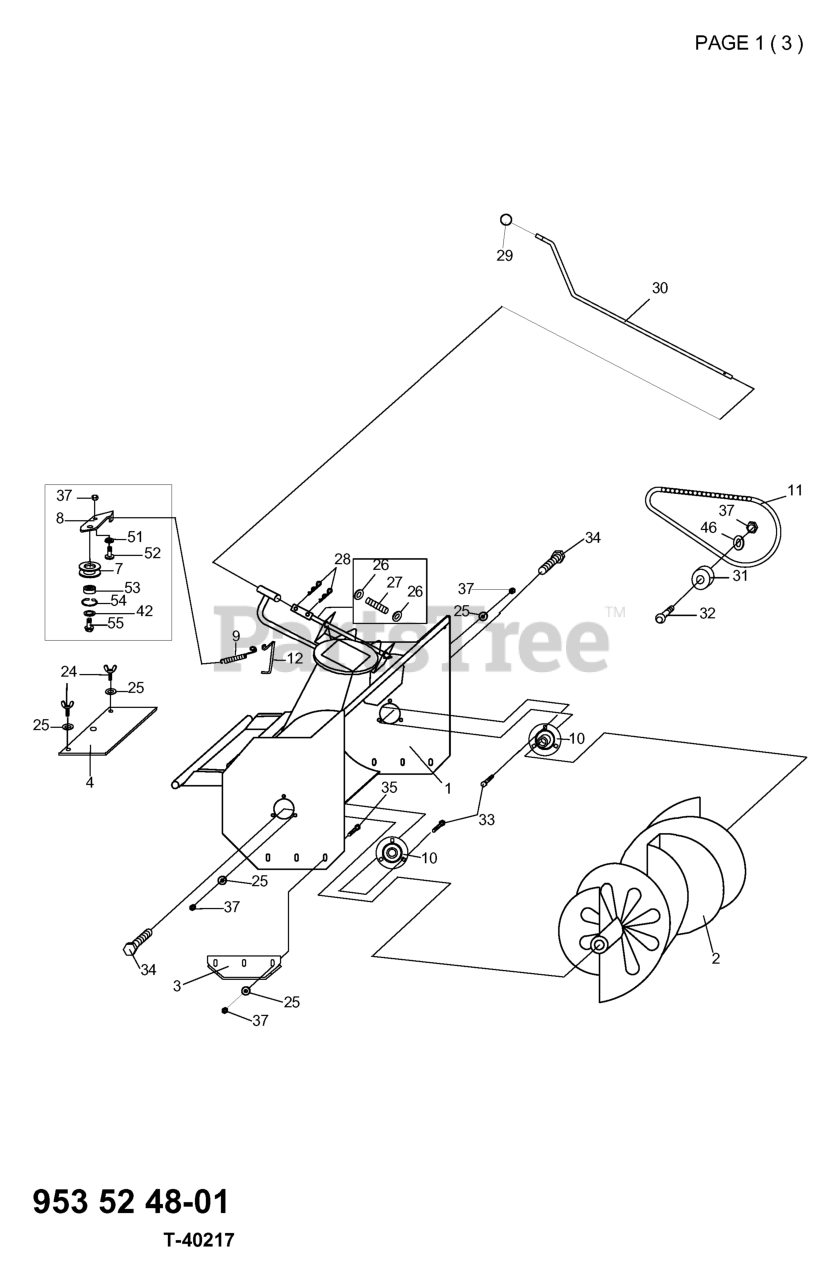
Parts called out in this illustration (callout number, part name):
7	%PULLEY
28	PIN RETAINING SCREW
31	CHAIN TENSIONER
51	SPACER
54	CIRCLIP
